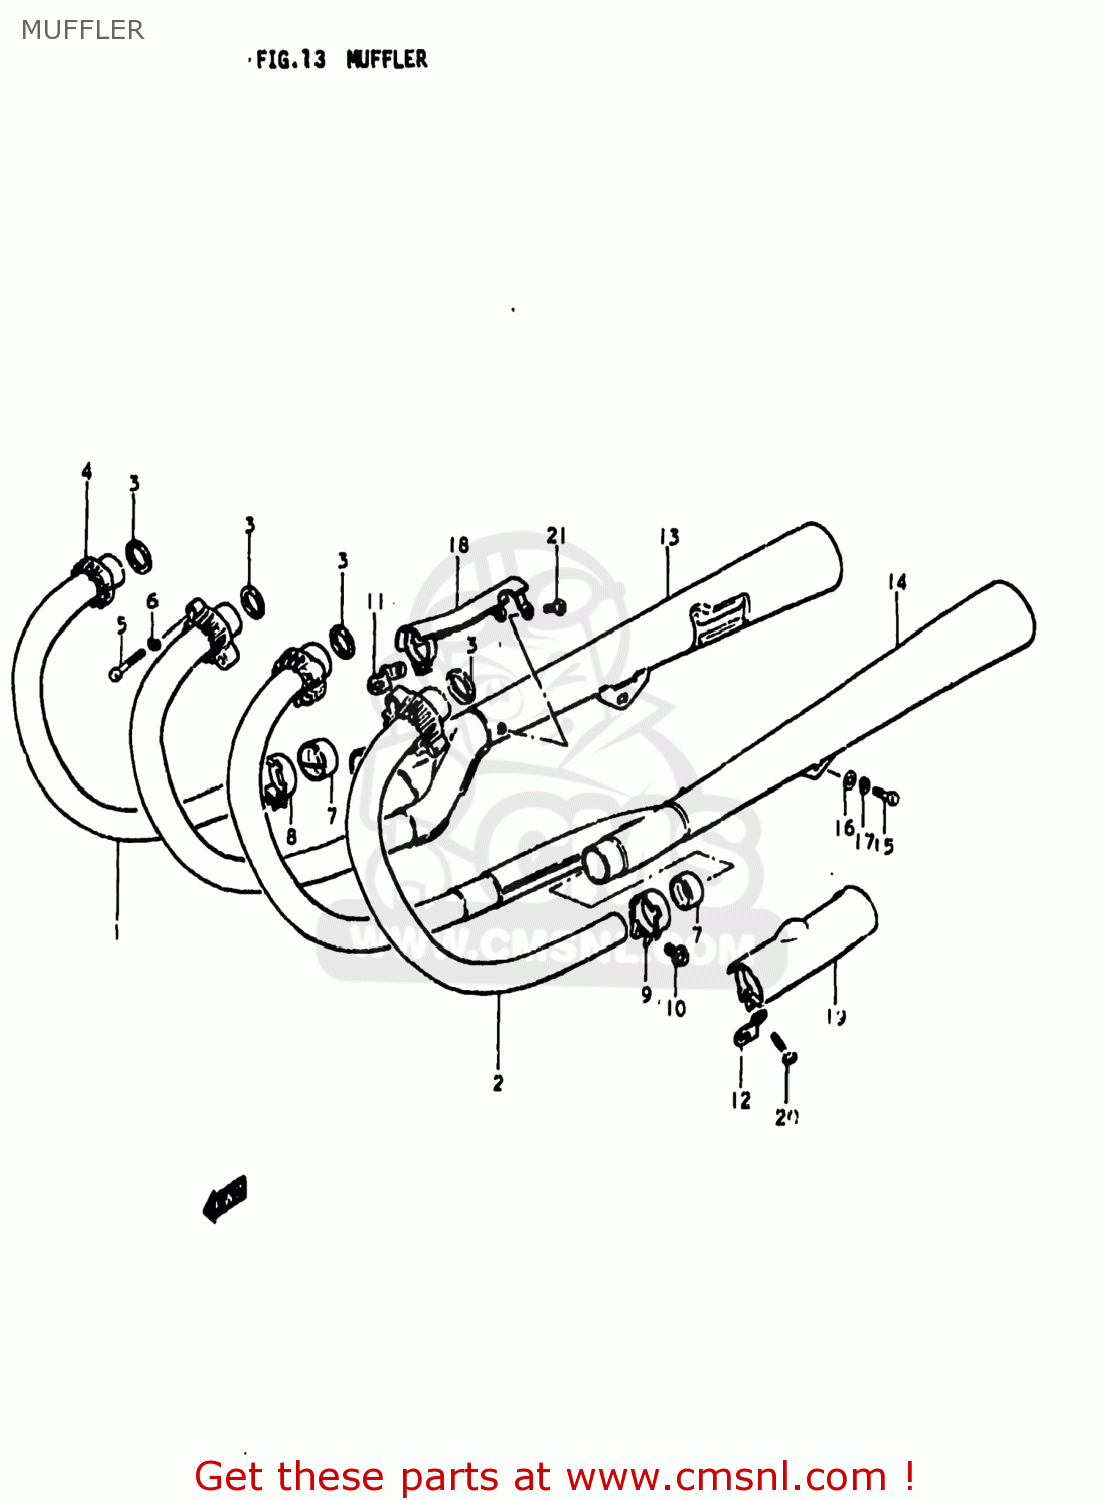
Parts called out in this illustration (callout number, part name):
1	PIPE,EXHAUST,RIGHT
2	PIPE,EXHAUST,LEFT
3	GASKET,EXHAUST PIPE (NAS)
4	CLAMP,EXHAUST PIPE
5	BOLT
6	LOCK WASHER
7	CONNECTOR,MUFFLER
8	CLAMP
9	CLAMP
10	BOLT
11	PLATE, CONNECTOR RH
12	PLATE, CONNECTOR LH
13	BODY,MUFFLER
14	BODY,MUFFLER
15	BOLT 10X30
16	WASHER
17	LOCK WASHER
18	COVER,MUFFLER
19	COVER,MUFFLER
20	SCREW 5X20
21	SCREW
